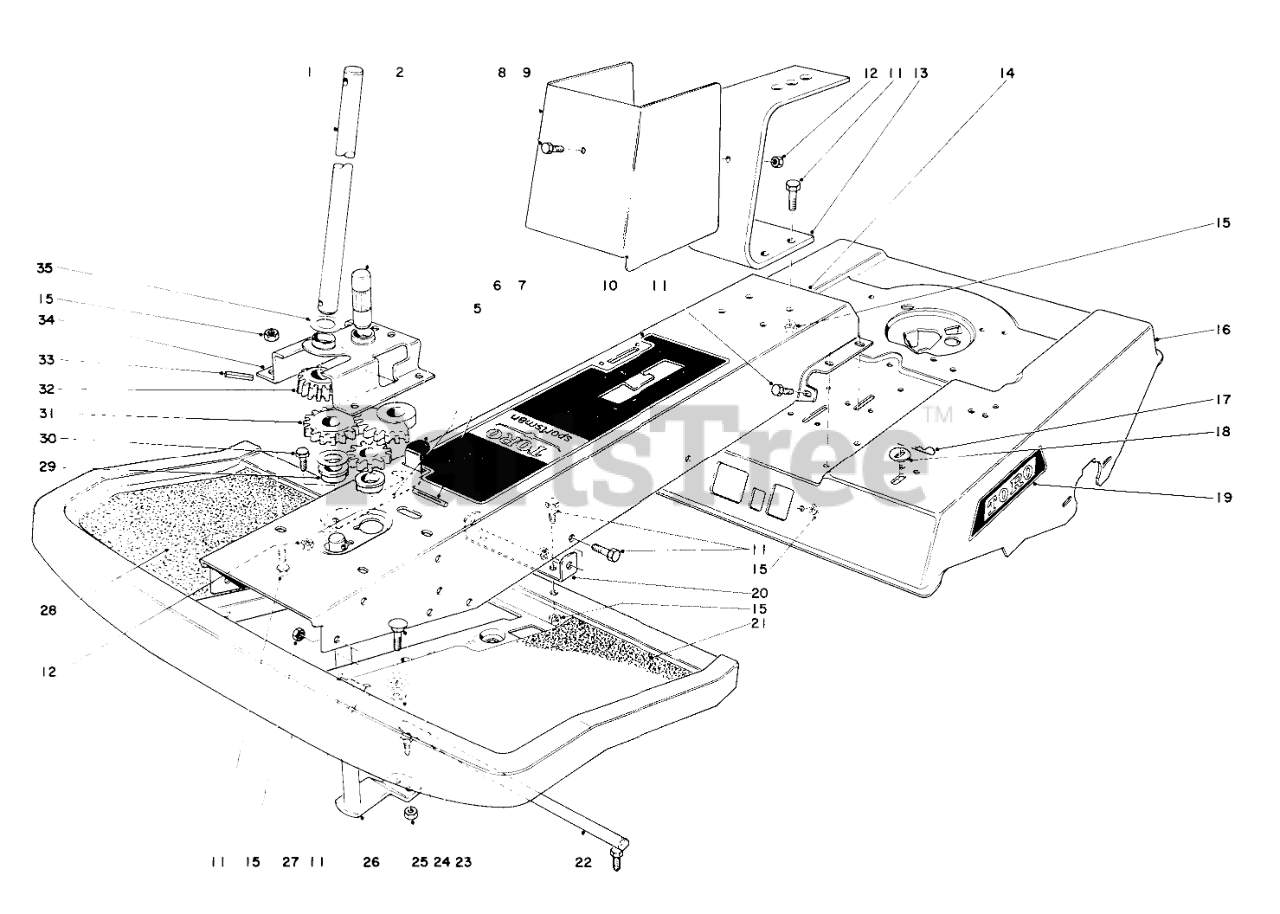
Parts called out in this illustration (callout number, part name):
1	Shaft Upper
2	Steering Idler Ass-y.
5	Parking Brake Tip
6	Parking Brake Spring
7	Groove Pin
8	SCREW-HH
9	Cover Seat
10	Decal (Model 56100)
11	SCREW-HH
12	NUT-LOCK
13	Seat Spring
14	Center Frame
15	Nut
16	Frame
17	PIN-COTTER
18	Washer
19	Decal
20	Support
21	Foot Pad L. H.
22	Ball Joint
23	SCREW-CARR
24	NUT-HF
25	Nut
26	Shaft
27	Foot Rest
28	Foot Pad R. H.
29	Bushing
30	SCREW-HH
32	STEERING PINION
33	PIN-ROLL, SLOTTED
34	Bracket Steering Support
35	Washer
